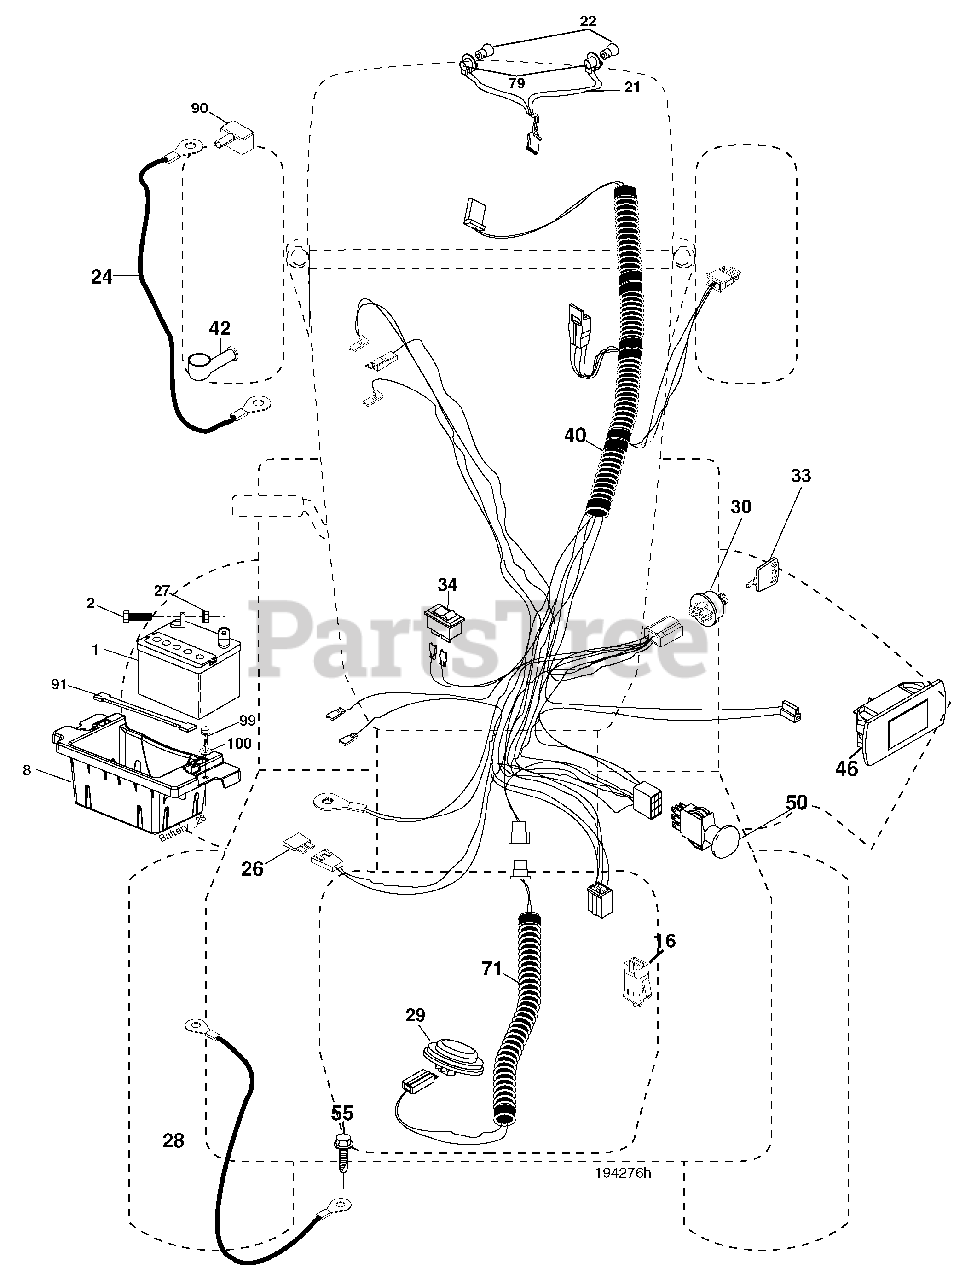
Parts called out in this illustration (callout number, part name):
1	Battery
2	Bolt Hex Head 1/4-20 x 3/4
8	Box Battery
16	Switch Interlock Push-In
21	Harness Socket Light W/4152J
22	Bulb Light
24	Cable Battery
26	Fuse
27	Nut Keps Hex 1/4-20 unc
28	Cable, Ground
29	Switch, Seat
30	Switch, Ignition
33	Key, Ignition
34	Switch Light / Reset
40	Harness Ignition
42	Cover, Terminal
46	Gauge Hourmeter
50	Switch, PTO
55	Screw Thdrol 5/16-18 x 3/4 TYTT
59	Outlet 12-Volt
71	Harness Ign. Dash
79	Bulbholder Asm. Incan Descent
90	Cover Terminal Battery
91	Strap Battery Mount Front
99	Screw Hexwsh Thdrol 1/4-20 x 3/4
100	Washer 9/32 x 7/8 x 16 Ga.
